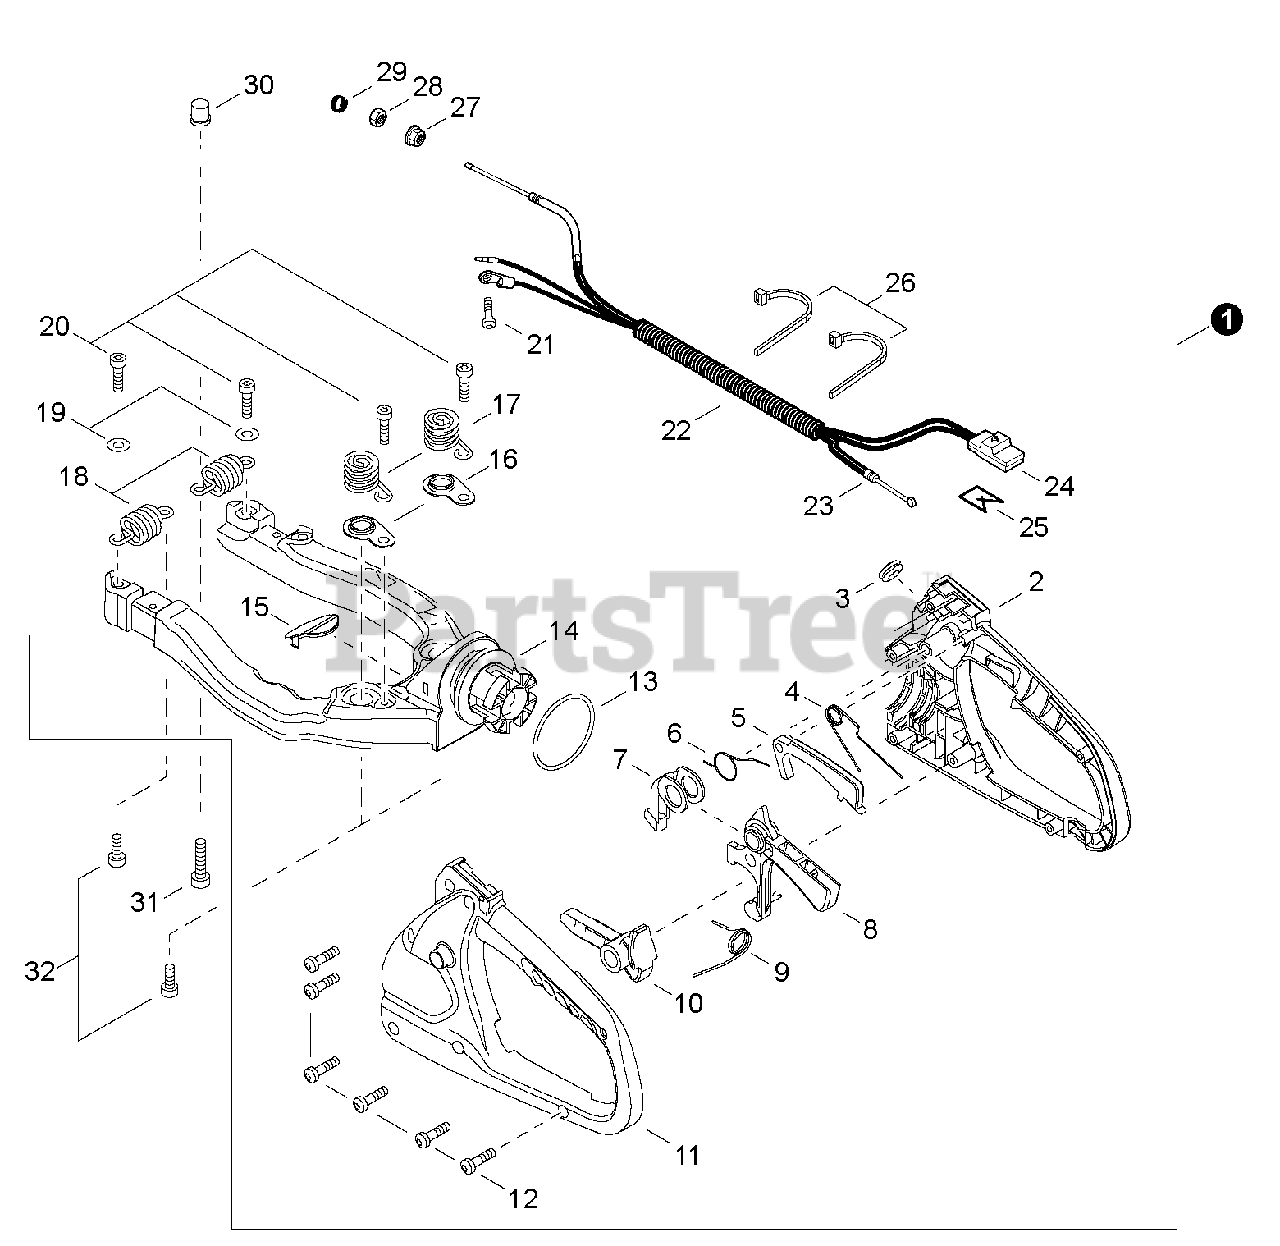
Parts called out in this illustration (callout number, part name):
1	HANDLE ASSY, REAR
2	HANDLE, RIGHT REAR
3	GROMMET
4	SPRING, TORSION
5	LOCKOUT, THROTTLE
6	SPRING, COIL
7	LEVER, THROTTLE
8	TRIGGER, THROTTLE
9	SPRING, TORSION
10	LEVER, HANDLE RELEASE
11	HANDLE, LEFT REAR
12	BOLT, TORX 4×16
14	FRAME
15	COVER, HANDLE
16	HOLDER, SPRING
17	SPRING, COMPRESSION
18	SPRING, COMPRESSION
20	BOLT, TORX 6×20
21	BOLT, TORX 4×8
22	TUBE, PROTECTIVE
23	CABLE, THROTTLE
24	SWITCH, ON-OFF
26	STRAP, TIE
27	NUT, FLANGE M6×1
31	BOLT, TORX 6×25
32	BOLT, TORX 6
